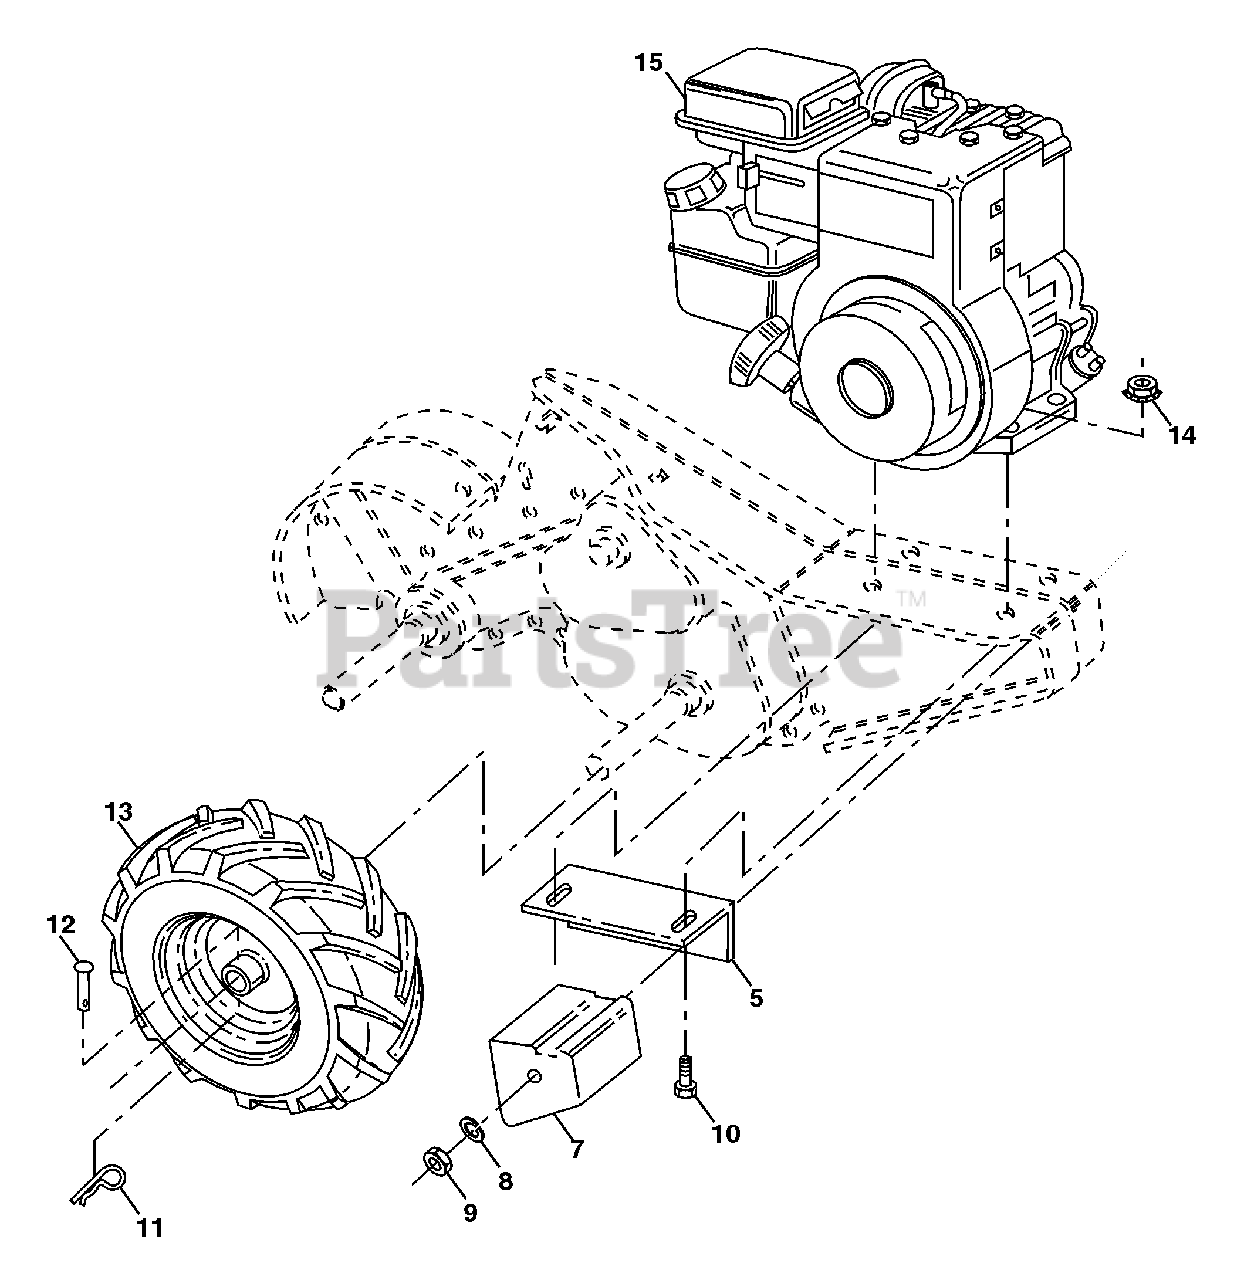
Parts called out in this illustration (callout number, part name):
5	Bracket, Reinforcement
6	Bolt, Hex 5/16-18 x 1-1/2
7	Counter Weight, R.H.
8	Washer, Lock 3/8
9	Nut, Hex 3/8-16
11	Clip, Hairpin
12	Rivet, Drilled
13	Tire
13	Tire Valve
14	Nut, Keps 5/16-18
